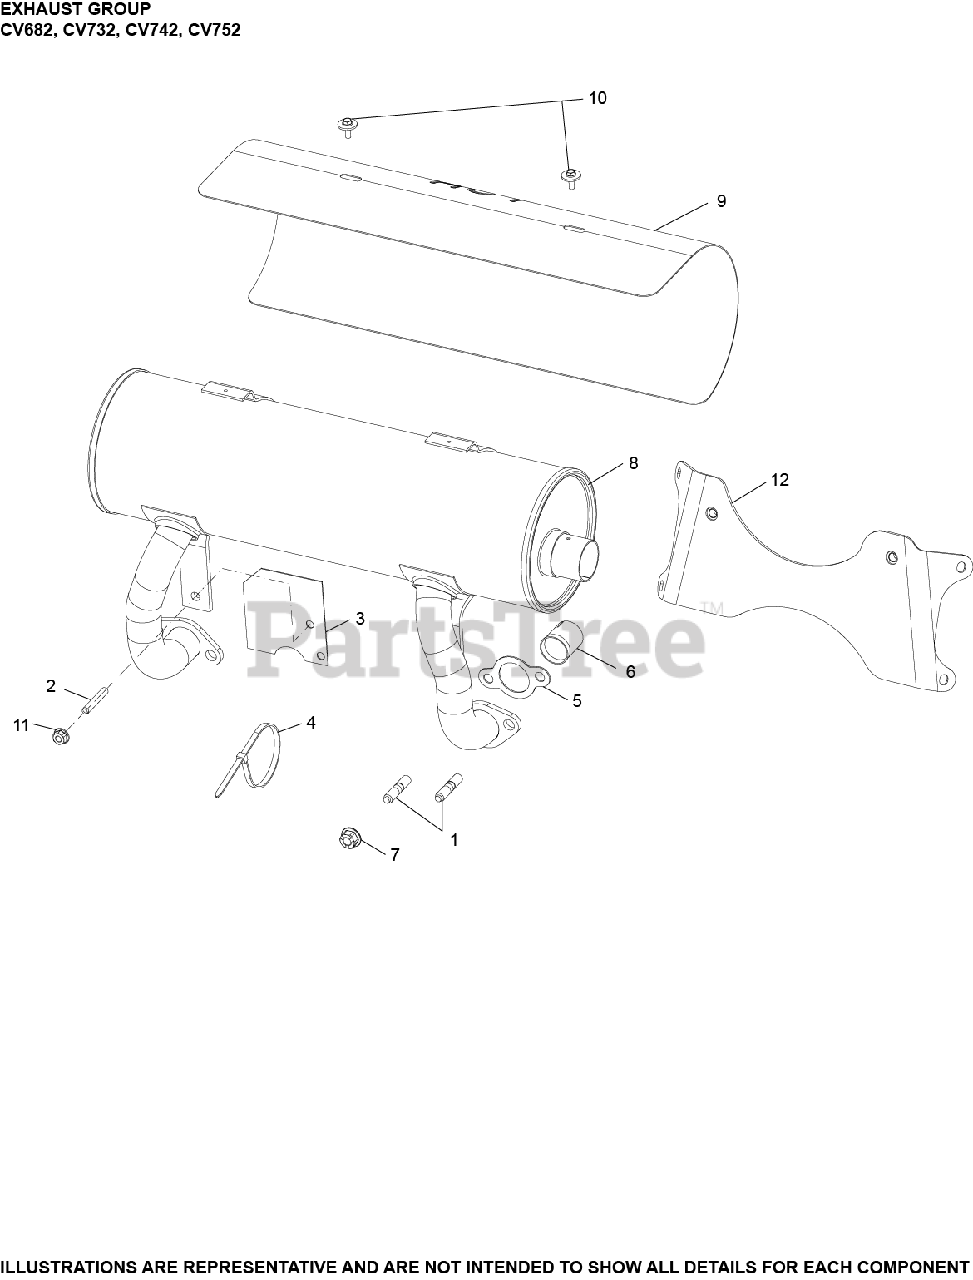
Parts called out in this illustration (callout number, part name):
5	GASKET, EXHAUST
6	LINER, EXHAUST PORT
7	NUT, HEX FLANGE LOCK (M8)
